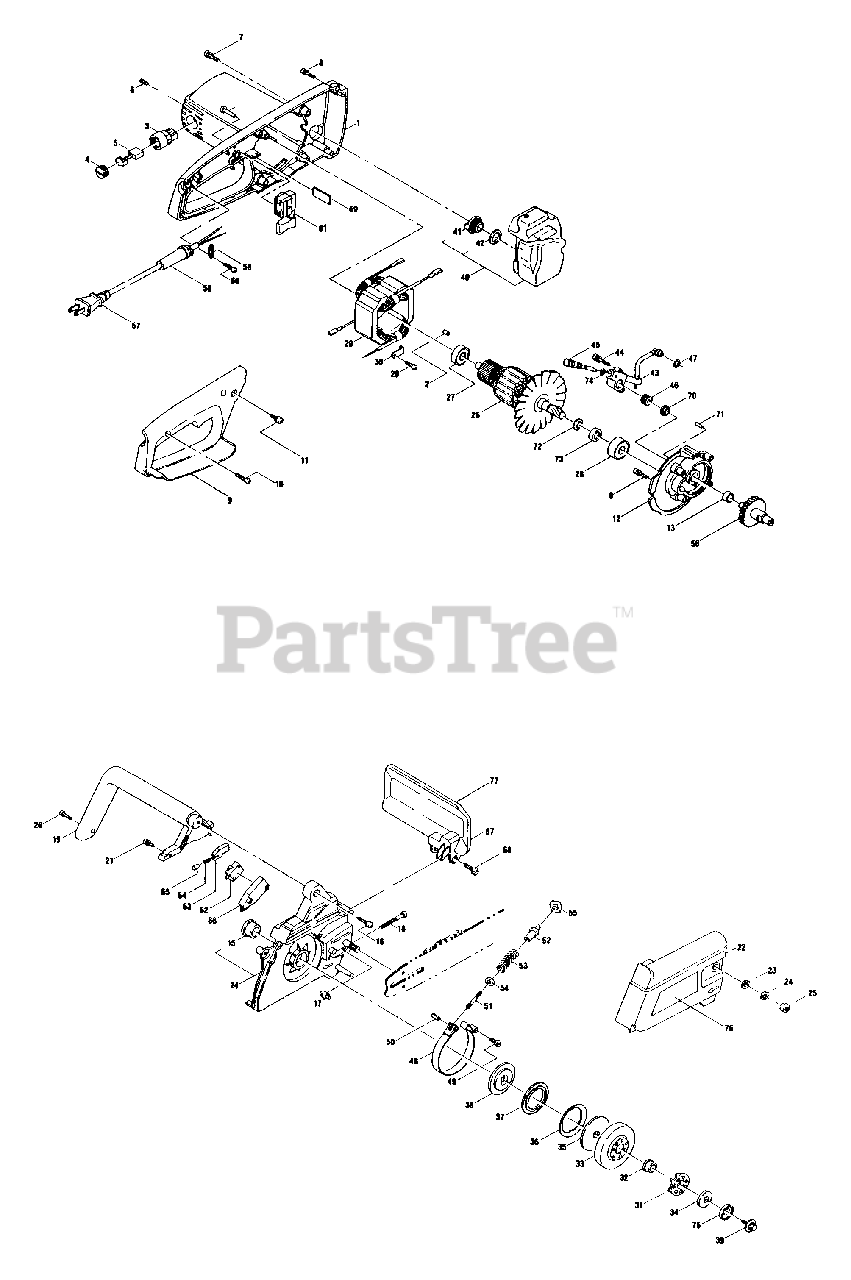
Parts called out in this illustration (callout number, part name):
1	CASE - LEFT
2	BUSHING
3	HOLDER, BRUSH
4	CAP
6	SCREW - 4X10
7	SCREW - 5X20
8	SCREW - 4X20
9	CASE - RIGHT
10	SCREW - TAPPING
11	SCREW - 5X8
12	GEAR CASE
13	BEARING, BALL - 607
14	GEAR CASE ASSY
16	SCREW -- TAPPING
17	TENSIONER, CHAIN
18	SCREW
19	HANDLE - FRONT
20	SCREW
21	SCREW - 4X16
22	BAR MOUNT ASSY
23	WASHER - 8
24	LOCKWASHER - 8
25	NUT - 8
26	ARMATURE
27	BEARING, BALL - 6200ZZ
28	BEARING, BALL - 6201
29	FIELD
33	DRUM, CLUTCH
35	PLATE, CLUTCH
36	DISK SPRING
40	OIL TANK ASSY
41	CAP, OIL
42	GASKET
43	OIL PUMP ASSY
44	SCREW - 4X20
45	PLUNGER
47	GASKET
48	BAND, BRAKE
49	BOLT
50	PIN - SPRING
51	ROD, ADJUST
52	SCREW, ADJUST
53	SPRING
56	GEAR CASE ASSY
57	POWER CORD
58	PROTECTOR, CORD
60	SCREW - TAPPING
61	SWITCH
62	SWITCH
63	SWITCH LEVER
64	SPRING
65	SWITCH, ROD
66	SWITCH, BOX
67	HAND GUARD ASSY
68	BOLT, LEVER
69	PLATE
71	PIN
72	RING, RETAINING
73	COLLAR
74	O-RING
76	NAME PLATE (A)
77	NAME PLATE (B)
